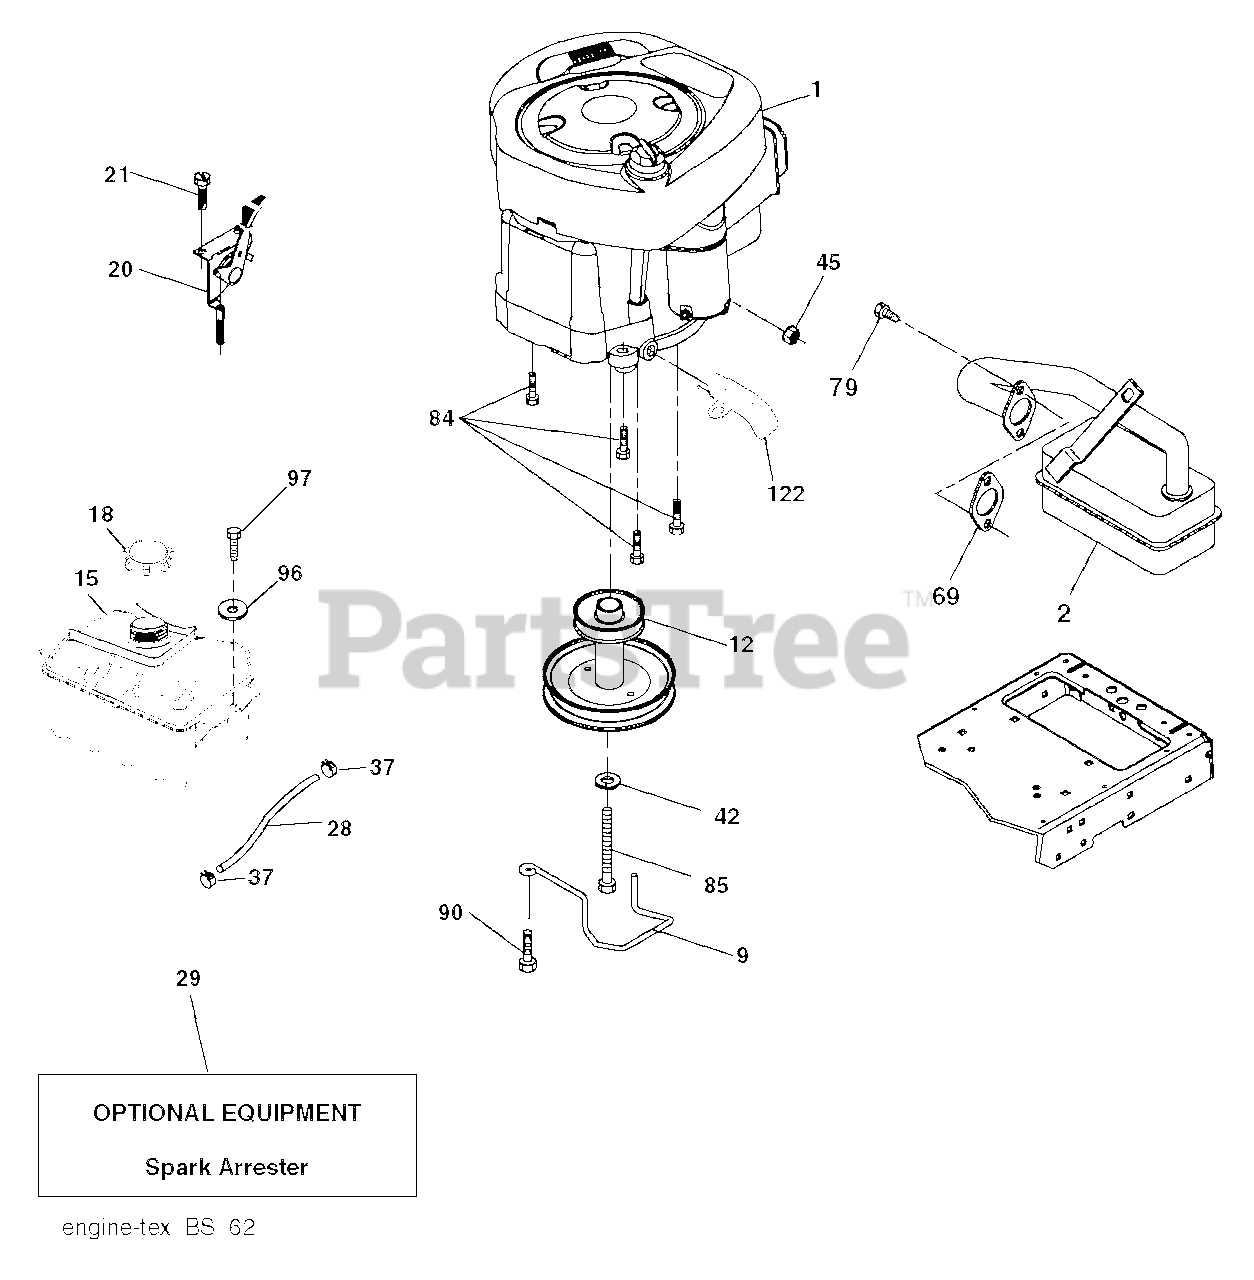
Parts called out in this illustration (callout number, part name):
2	MUFFLER.LT.BRIGGS.14HP.IC/OHV
9	KEEPER.BELT.ENGINE.4.2
12	PULLY ENGINE
15	RP TANK FUEL FRT 1.5 GAL
18	CAP ASM.FUEL.2.25"FR.
20	CONTROL.TH/CK.C.
21	SCREW.#10 X 0.750.BOS
28	LINE.FUEL.20"FRONT.EMI
29	KIT.SPARK ARRESTOR 794945 B&S
37	HOSE CLAMP
42	LOCKWASHER
45	NUT
69	REPL BY 532 27 22-93
79	SCREW.SOCKET HD.5/16-1
84	SCREW.3/8-16
85	BOLT HEX 7/16-20X4-1/4"
90	SCREW 3/8-16X1
97	SCREW HEXWSHR 1/4-20X3/4
122	EXTENSION DRAIN OIL
